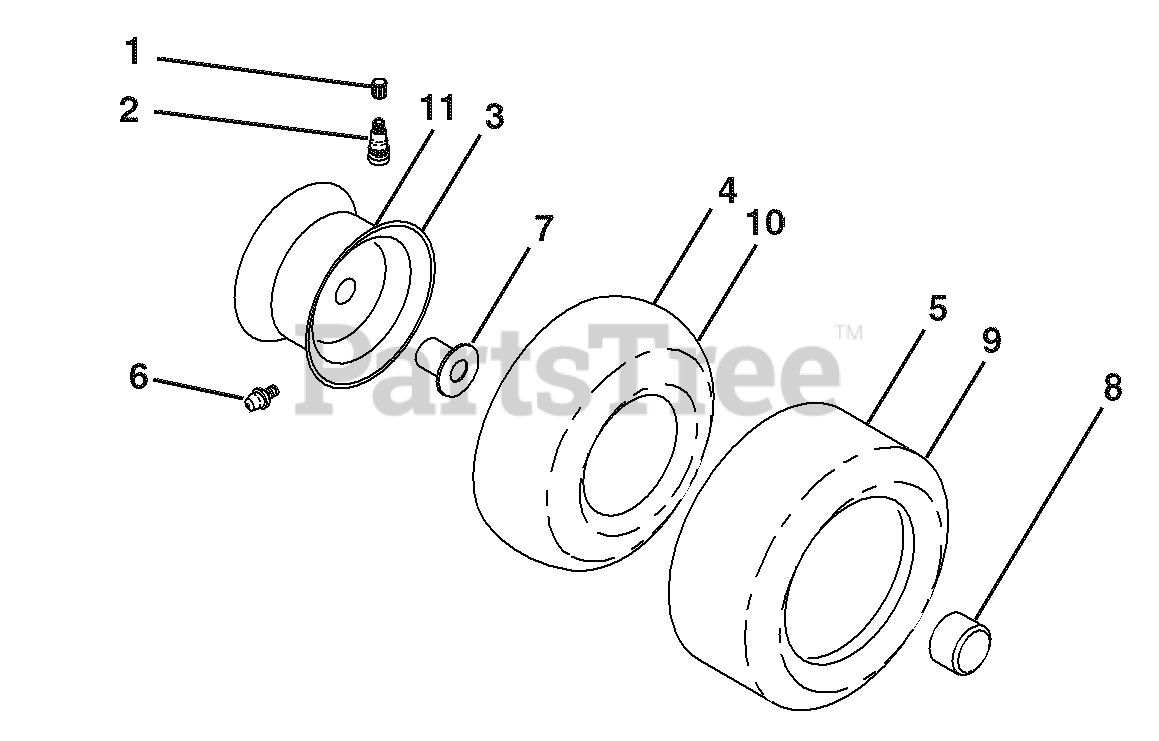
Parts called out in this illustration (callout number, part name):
1	Cap, Valve, Tire
2	Stem, Valve
3	Rim Assembly, Front
4	Tube, Front
5	Tire, Front
6	Fitting, Grease
7	Bearing, Flange
8	Cap, Axle
10	Tube, Rear
11	Rim Assembly, Rear
